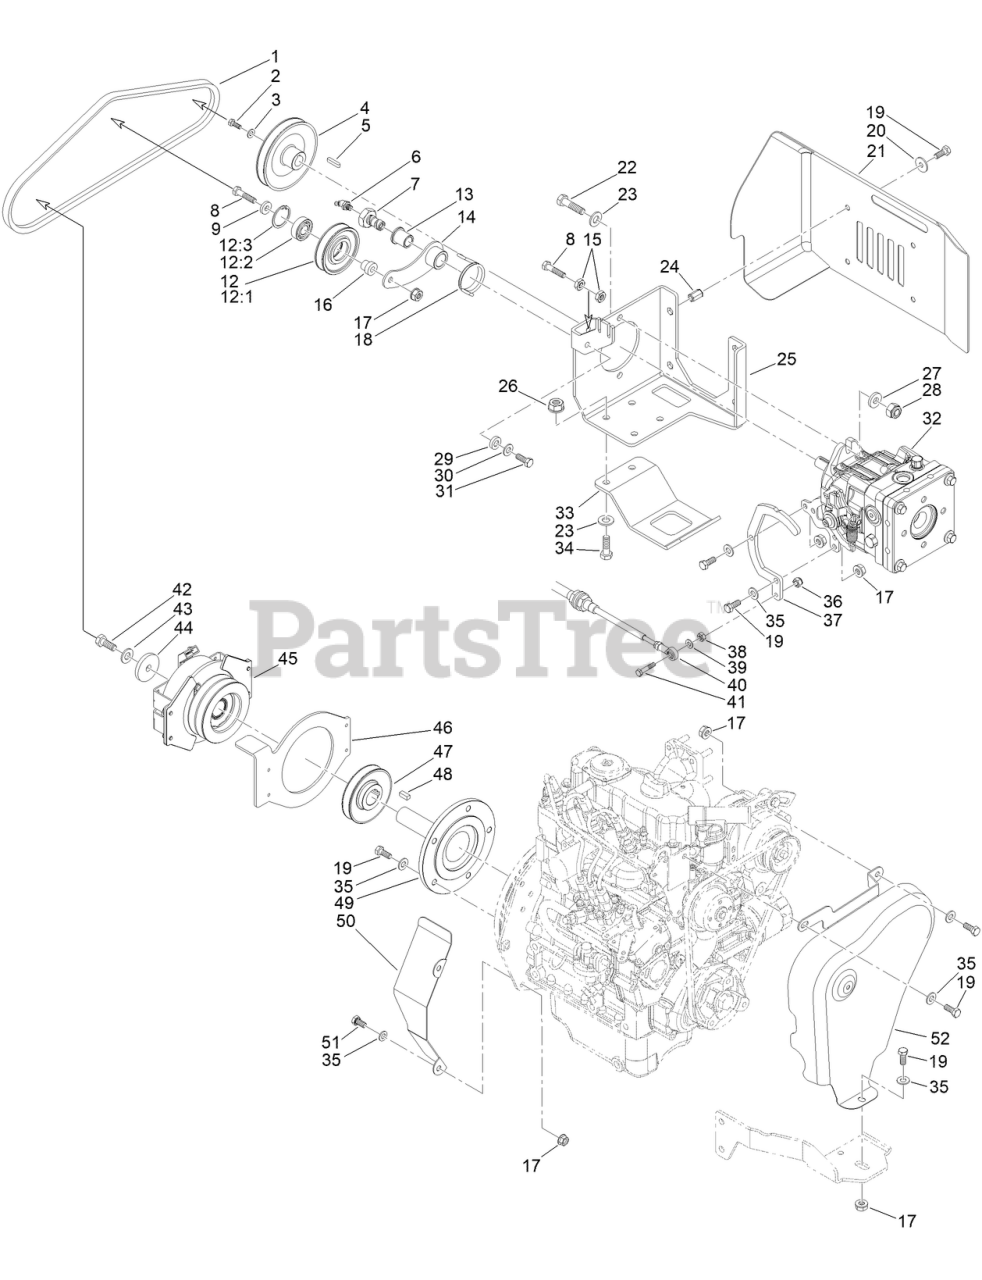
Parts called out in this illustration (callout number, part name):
1	BELT, TRANSMISSION PUMP
3	WASHER
4	PULLEY, TRANSMISSION PUMP
6	FITTING-GREASE
7	PIVOT, BELT TENSIONER
9	WASHER
12	PULLEY ASSY, BELT TENSIONER
12:1	PULLEY, BELT TENSIONER
12:2	BEARING
12:3	RETAINER
13	BUSHING
14	BRACKET,TRANSMISSION PUMP BELT TENSIONER
16	BUSHING, BELT TENSIONER
18	SPRING-TORSION
20	WASHER
21	COVER, TRANSMISSION PUMP
23	WASHER
24	INSERT-HEX
25	SUPPORT, TRANSMISSION PUMP
27	WASHER
29	WASHER
30	WASHER
31	SCREW-HH
32	PUMP, TRANSMISSION
33	SKID, TRANSMISSION PIPES
35	WASHER
37	BRACKET, NEUTRAL SWITCH
39	WASHER
40	CABLE, TRANSMISSION
41	SCREW-HH
43	WASHER
44	WASHER
45	CLUTCH, GT1.5-GR15D
46	BRAKE, CLUTCH
47	PULLEY, ENGINE
49	SHAFT, ENGINE
50	COVER, ENGINE FLYWHEEL
52	COVER, ENGINE BELT
